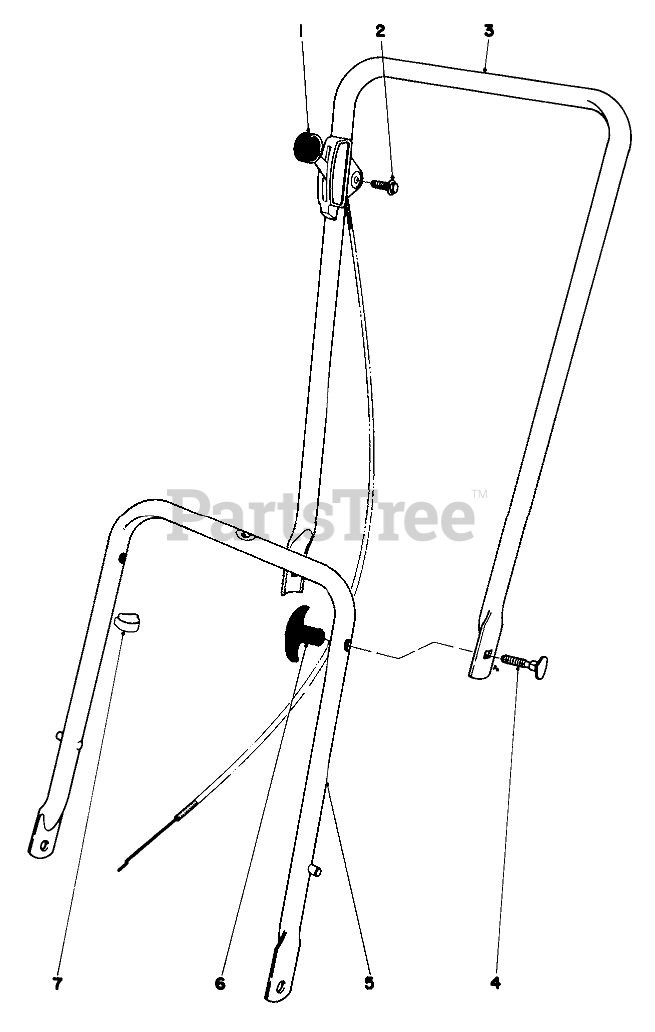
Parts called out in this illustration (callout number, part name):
1	Throttle Control
2	Hex Hd. Thread Forming Screw
3	UPPER HANDLE
4	HANDLE SCREW
5	Lower Handle
